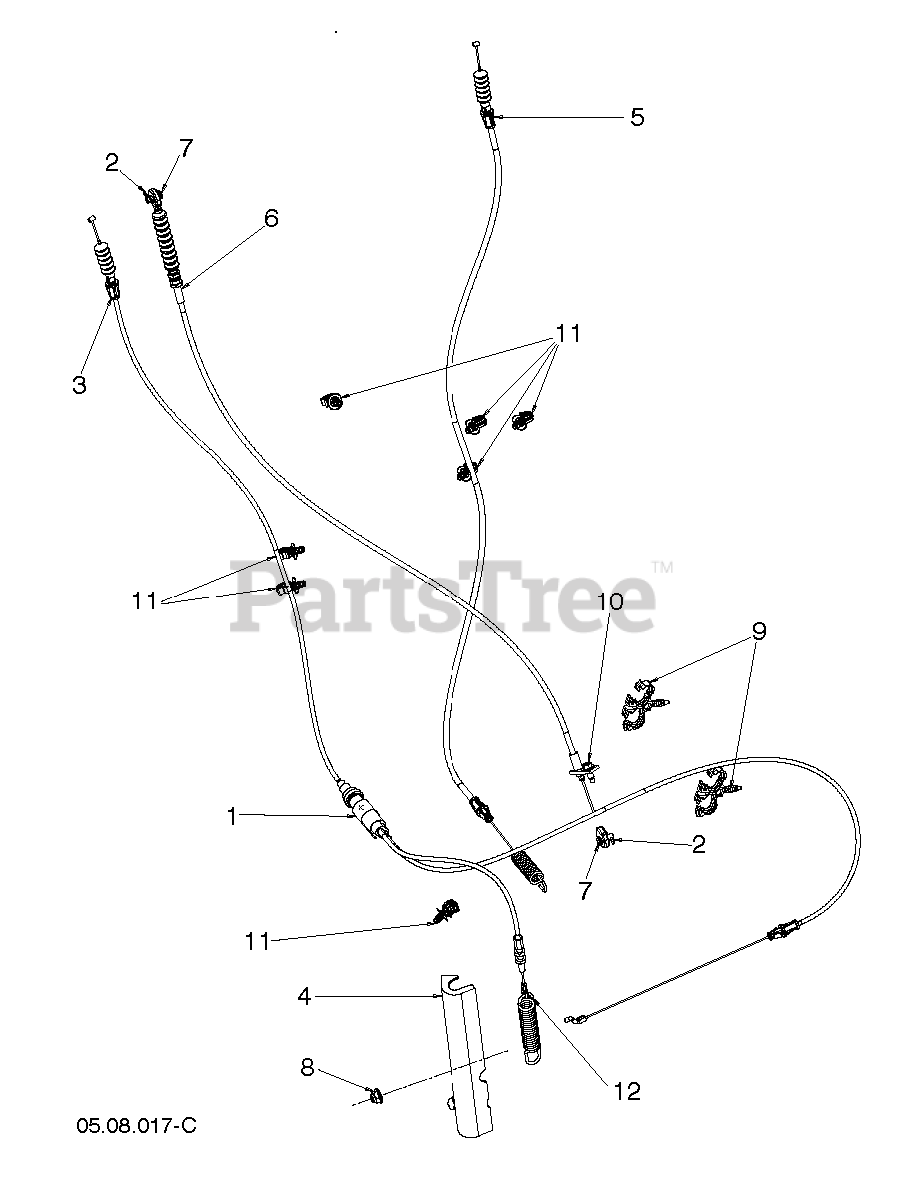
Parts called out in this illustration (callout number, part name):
1	CLIP.CABLE.BLK
2	HAIRPIN.SOFT.ZINC.059X1.125
3	CABLE IMPELLER
4	COVER AUGER CABLE
5	CABLE ASSY DRIVE
6	CABLE HYDRO SPEED
7	PIN CLEVIS .25 X ..4375
8	NUTNYLOK.FLRANGE.5/16-18
9	CLIP.CONDUIT.DOUBLE LOOP
10	HEX.WASHER.HEAD 1/4-20 X .65
11	CABLE, 1/4 BLACK FIR TREE
12	SPRING EXTENSION; AUGER EXTENS
